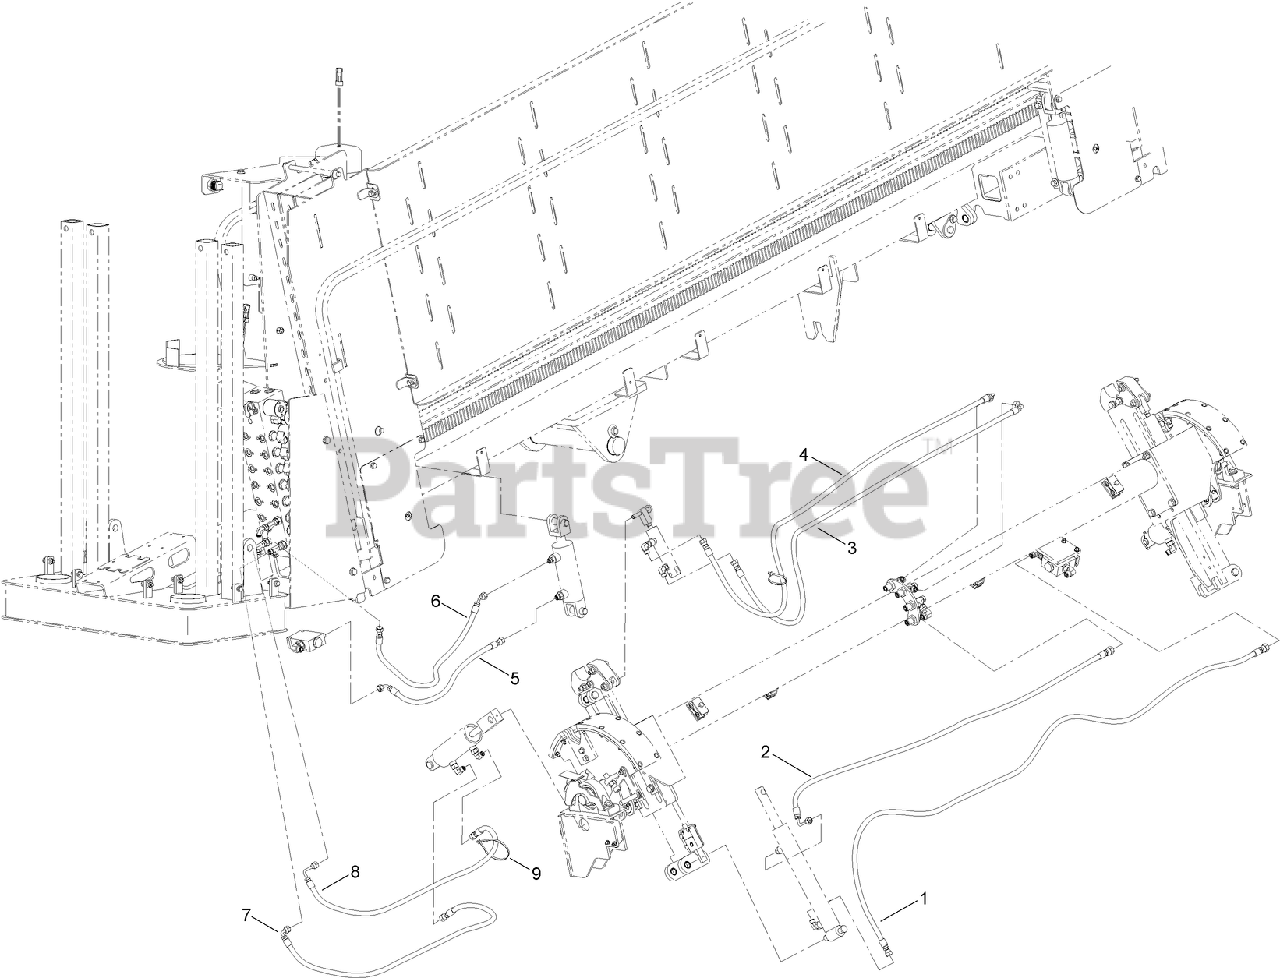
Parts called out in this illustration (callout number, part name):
1	HOSE ASM
2	HOSE ASM
3	HOSE ASM
4	HOSE ASM
5	HOSE ASM
6	HOSE ASM
7	HOSE ASM
8	HOSE ASM
9	TIE-CABLE
